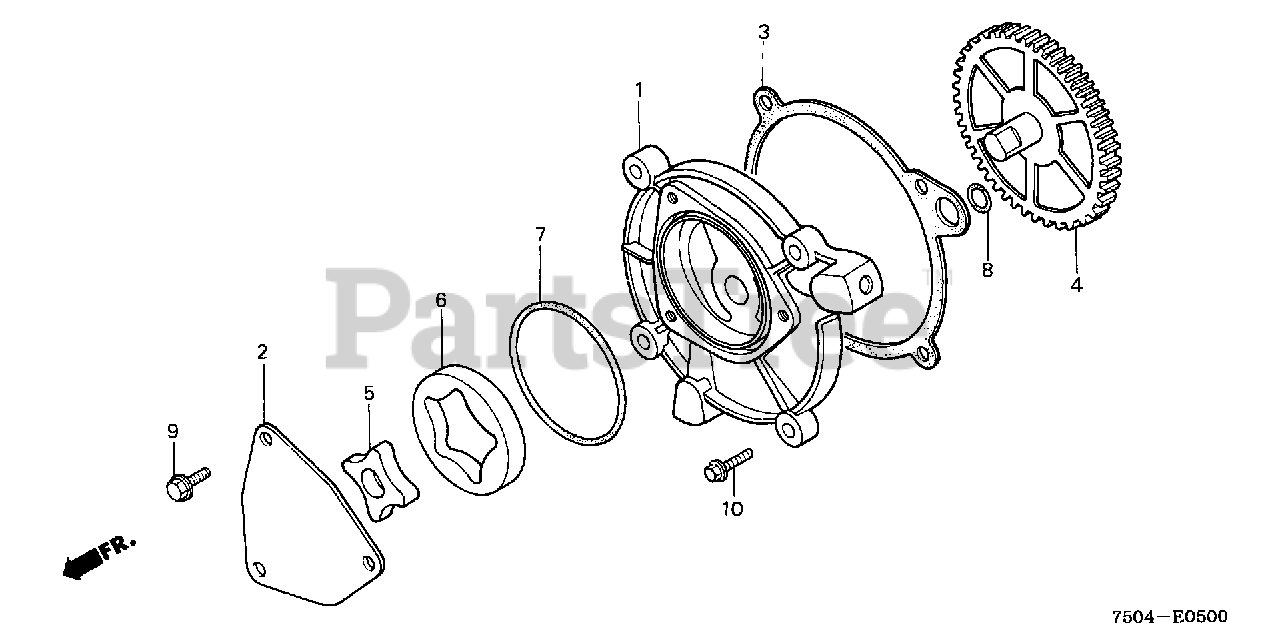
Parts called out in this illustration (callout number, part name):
1	BODY, OIL PUMP
2	COVER, OIL PUMP
3	GASKET, OIL PUMP
4	GEAR ASSY., OIL PUMP
5	ROTOR (INNER)
6	ROTOR (OUTER)
7	O-RING (45X2.5) (ARAI)
7	O-RING, PUMP COVER
8	O-RING (10.8X2.4) (ARAI)
9	BOLT, FLANGE (6X12)
10	BOLT, FLANGE (6X28)
